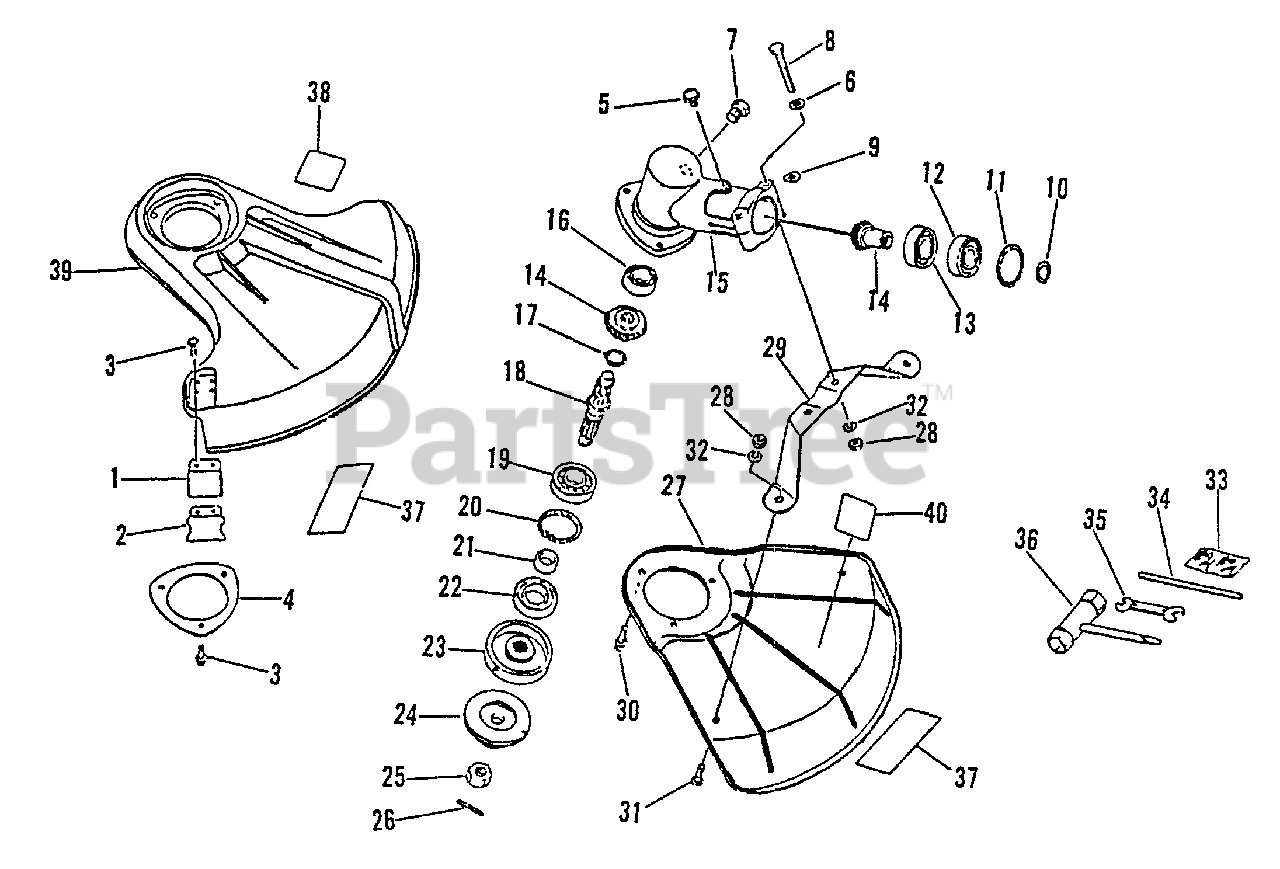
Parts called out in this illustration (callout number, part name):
1	KNIFE, TRIMMER LINE
2	PROTECTOR
3	SCREW 5×16
4	PLATE, SHIELD Ø49.5 MM
5	SCREW 5×10
6	WASHER, FLAT 5.5×10×0.8
7	BOLT 8×8 SP
8	BOLT 5×40
10	RING, RETAINING - 12
11	RING, SNAP 28
12	BEARING, BALL 6001
13	BEARING, BALL 6001
14	GEAR SET
15	CASE, GEAR
16	BEARING, BALL 6000
17	RING, SNAP Ø12
18	SHAFT, GEAR
19	BEARING, BALL - 6201 C3
20	RING, SNAP Ø32
21	SPACER 11.8×15×9
22	SEAL, OIL 22
23	PLATE, ADAPTER - UPPER
24	PLATE, ADAPTOR - LOWER
26	PIN, COTTER 2×22
27	DEBRIS SHIELD KIT - BLADE
28	NUT M5
29	BRACKET, SHIELD MOUNTING
30	SCREW 5×10
31	SCREW 5×8
32	WASHER, SPRING 5
33	PIN, COTTER 2×22 (PKG. OF 10)
34	TOOL, LOCKING 5×120 MM
35	SPANNER 8×10
36	T-WRENCH 17x-19 L200
37	LABEL, ECHO
38	LABEL, CAUTION
39	DEBRIS SHIELD KIT
40	LABEL - CAUTION
